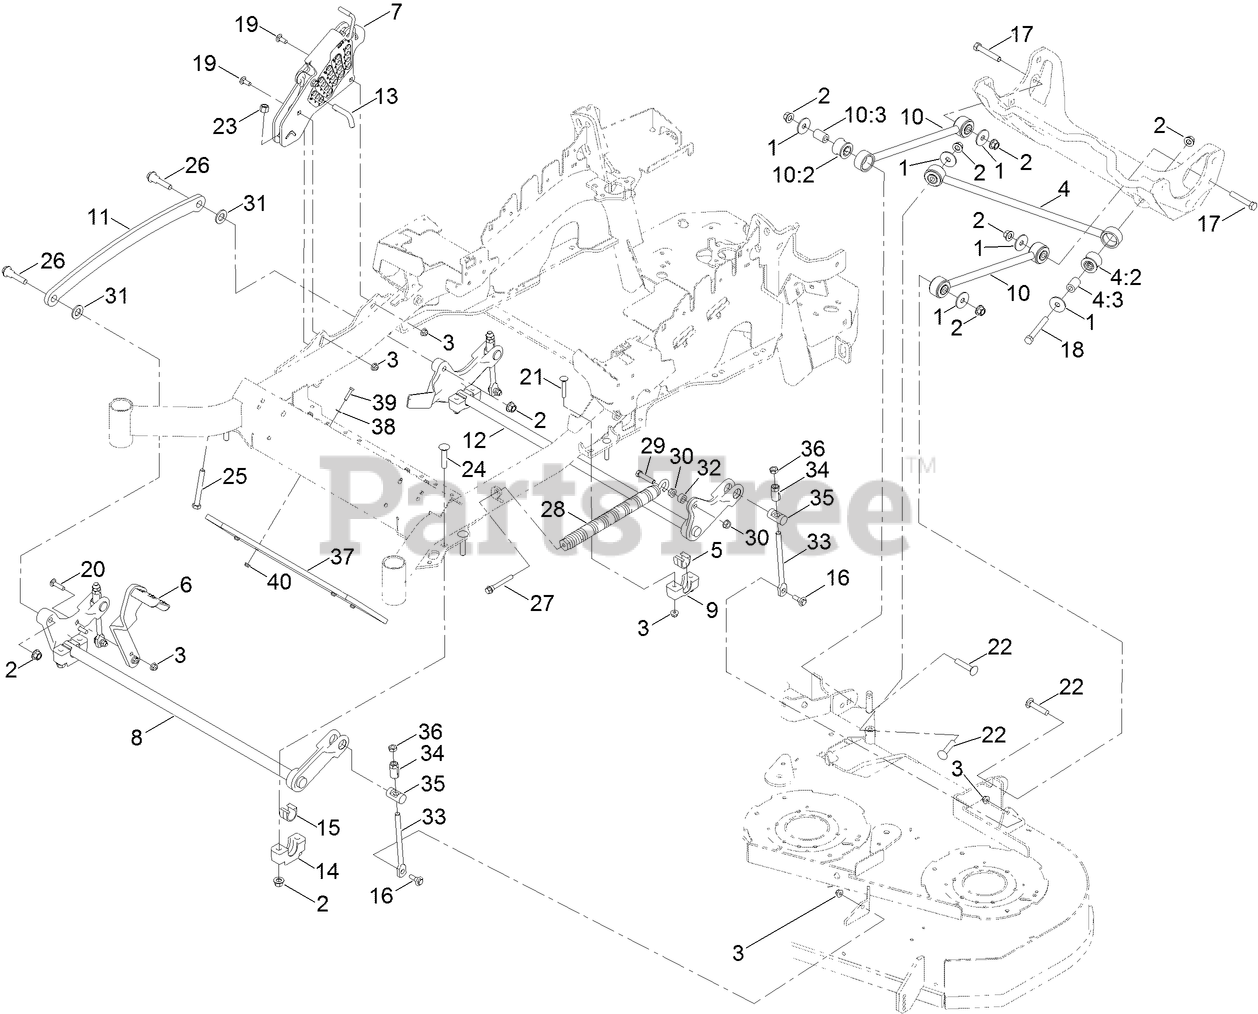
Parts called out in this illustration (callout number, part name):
1	WASHER-THRUST
2	NUT-LOCK
3	NUT-HF, NI
4	PANHARD ROD ASM
4:2	BUSHING-SUSPENSION, RUBBER
4:3	SPACER
5	BEARING-CROSS SHAFT, REAR
6	LEVER-FOOT
7	HOC ASM
8	DECKLIFT-FRONT
9	SUPPORT-CROSS SHAFT, BEARING REAR
10	DECK STRUT ASM
10:2	BUSHING-SUSPENSION, RUBBER
10:3	SPACER
11	LINK-LIFT, DECK
12	LIFT-DECK, REAR
13	PIN-HOC
14	SUPPORT-CROSS SHAFT, BEARING
15	BEARING-CROSS SHAFT, FRONT
16	SCREW-SHOULDER, HHF
17	SCREW-HH
18	SCREW-HH
19	BOLT-CARR
20	SCREW-CARR
21	SCREW-CARR
22	SCREW-CARR
23	NUT-LOCK, NI
24	BOLT-CARR
25	BOLT-TAP
26	SCREW-HHF, SHOULDER
27	BOLT-SHOULDER
28	SPRING-EXTENSION
29	SCREW-HH
30	NUT-HF
31	WASHER-FLAT
32	SPACER
33	LINK-ADJUSTER, DECK LIFT
34	ADJUSTER-LIFT, DECK
35	TRUNNION
36	NUT-JAM
37	WEIGHT-TOE BOARD
38	WASHER-FLAT
39	SCREW-HH
40	NUT-HF
